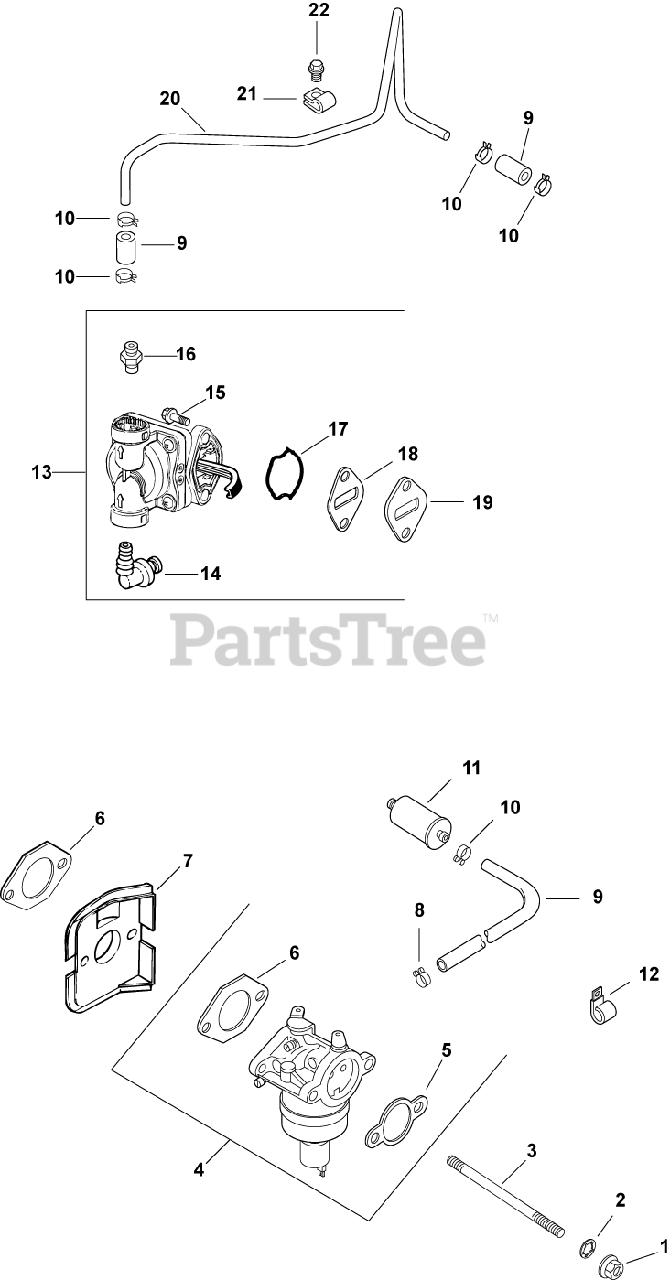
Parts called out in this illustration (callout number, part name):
1	NUT, FLG M6X1.0
2	WASHER, INT TOOTH LOCK 1/4"
3	STUD,M6X1.0X116
4	KIT, CARBURETOR
5	GASKET, AIR CLEANER BASE
6	GASKET, CARBURETOR
7	DEFLECTOR, HEAT - DISCONTINUED
8	CLAMP, BAND SPRING HOSE-(#2523737S)
9	HOSE,LW PERM.FUEL 24.00"-USE 25 111 81-S
10	CLAMP, HOSE (KM)-USE 25 237 31-S
11	FILTER,FUEL 51 MICRON (FUEL PUMP)
12	CLIP, CABLE
13	KIT, FUEL PUMP
14	CONNECTOR, 90 DEG. HOSE
15	SCREW, LBD SKT M6x1.0x20-(#25086403S)
16	KIT, STRAIGHT FITTING
17	O-RING, FUEL PUMP
18	GASKET, FUEL PUMP
19	SPACER, FUEL PUMP
20	LINE, FUEL
21	CLIP, TUBE & WIRING (KM)
22	SCREW, FLG THD FRM M5X.8X10
